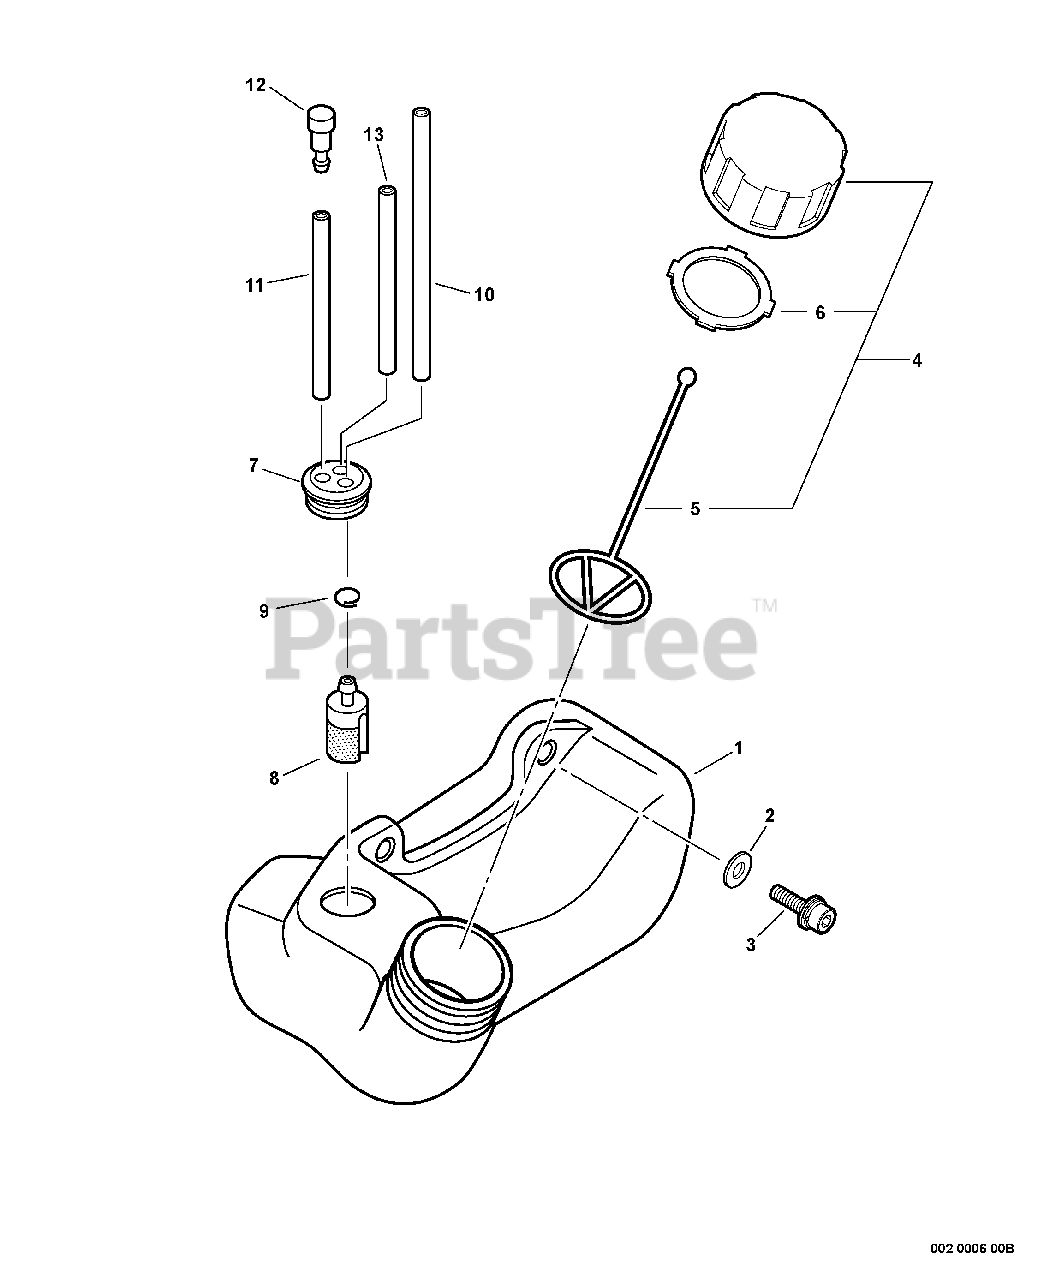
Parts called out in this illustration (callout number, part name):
1	TANK, FUEL
2	WASHER 5.5×12×0.8
3	BOLT 5×20
4	CAP ASSY, FUEL
5	CONNECTOR, CAP L= 100 MM
6	GASKET, FUEL CAP
7	GROMMET, FUEL
8	FILTER, FUEL
9	CLIP 6 MM
10	PIPE, FUEL 3x-5x-180
11	PIPE, FUEL 3x-5x-70 BLACK
12	VENT ASSY
13	PIPE, FUEL 3×6×80 CLEAR
